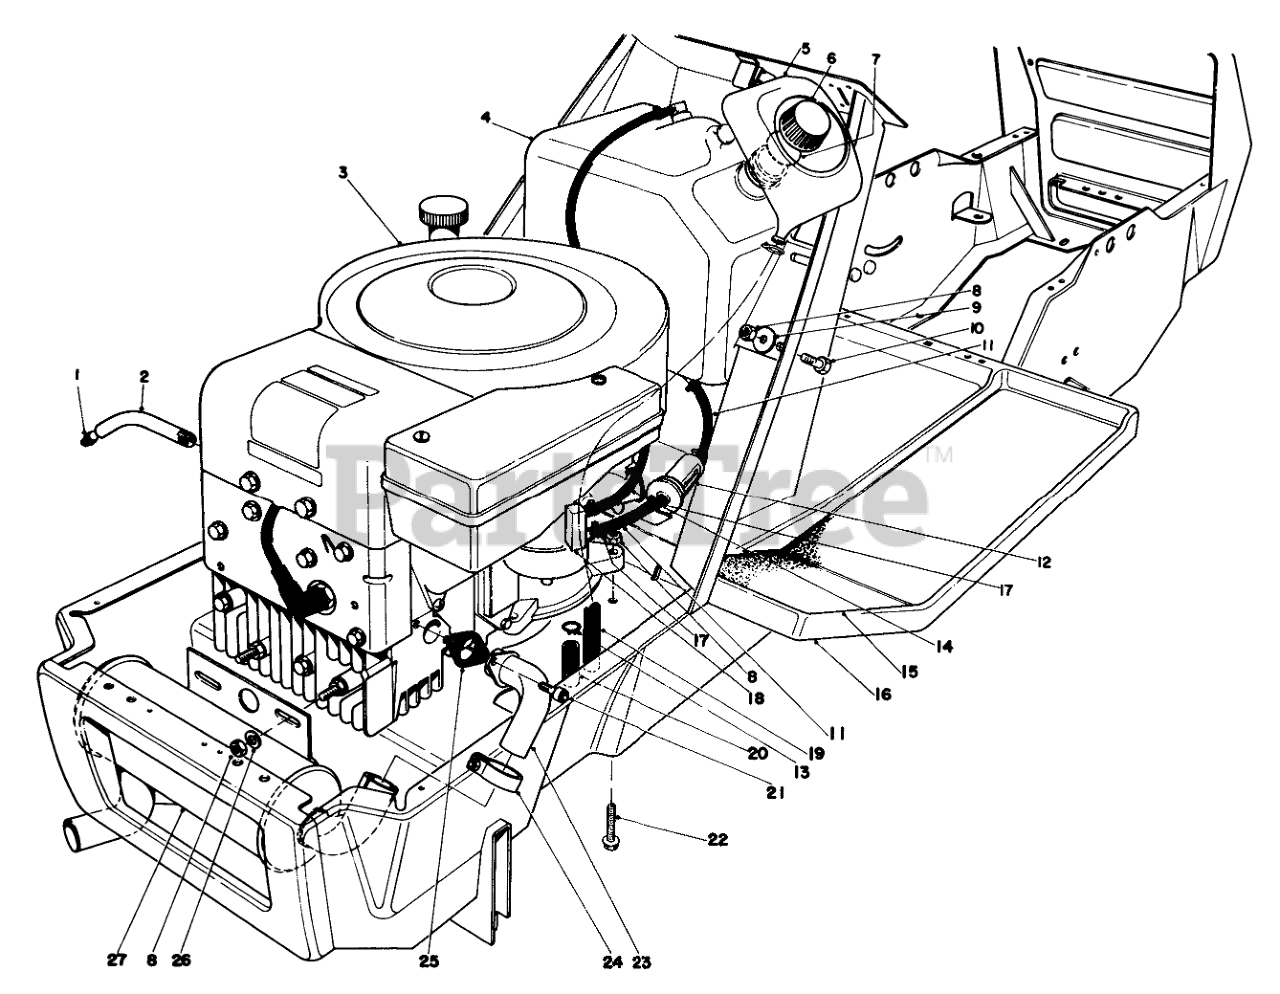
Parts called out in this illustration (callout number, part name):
1	PLUG-PIPE, SQH
2	OIL DRAIN TUBE
3	Engine
4	Gas Tank Assembly (Incl. Ref. #5)
5	Funnel Overflow
6	Gas Cap Assembly (Incl. Ref. #7)
7	Gasket Gas Cap
8	NUT-LOCK, CONE
9	WASHER
10	SCREW-HH
11	GAS HOSE
12	Fuel Filter
13	HOSE CLAMP
14	Gas Return Hose
15	LH FOOT TREAD
16	Frame
17	CLAMP-HOSE
18	Fitting Carburetor
19	FUNNEL HOSE
20	CARB DRAIN HOSE
21	SCREW-HSH
22	SCREW-HH
23	10 HP EXHAUST PIPE WA
24	MUFFLER CLAMP
25	Exhaust Gasket
26	WASHER-PLAIN
27	EXHAUST MUFFLER 10 HP
